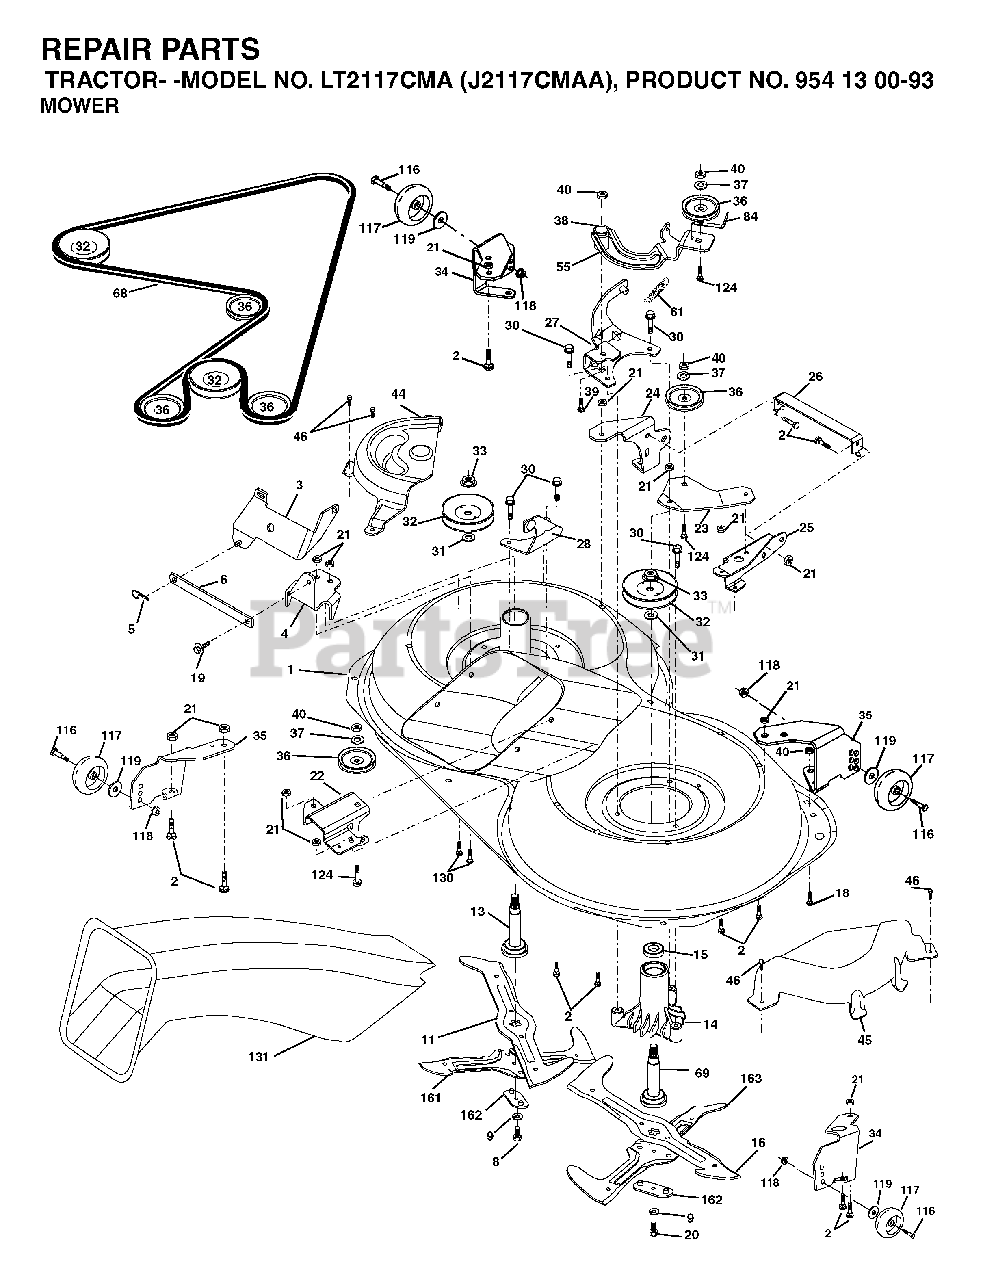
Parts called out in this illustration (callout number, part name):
2	BOLT
3	BRACKET
5	RETAINER-SPRNG RB
6	BAR SWAY
9	LOCKWASHER
11	BLADE.3N1.LH.CRD
13	SHAFT ASM VENT
14	HSG MANDREL
16	BLADE.3N1.RH.CRD
19	BOLT SHD 5/16-18
21	LOCKNUT
22	BRACKET
23	BRACKET
26	BRACE
27	BRACKET
30	SCREW, WASHER HEAD
31	WASHER
33	NUT, FLG TOPLOCK 9/16"
36	PULLEY.IDLER.4.25
40	LOCKNUT
45	MANDREL COVER
46	SCREW.1/4-20X5/8
55	ARM IDLER
68	HEX-BELT 107 MOWER
69	SHAFT.ASM.W/LWR.BRG.RH.THREAD
84	KEEPER, BELT IDLER
116	SHOULDER BOLT
117	WHEEL GAGE DONUT
118	LOCKNUT
119	WASHER
124	BOLT.3/8-16X1.50
131	CHUTE BAGGER
